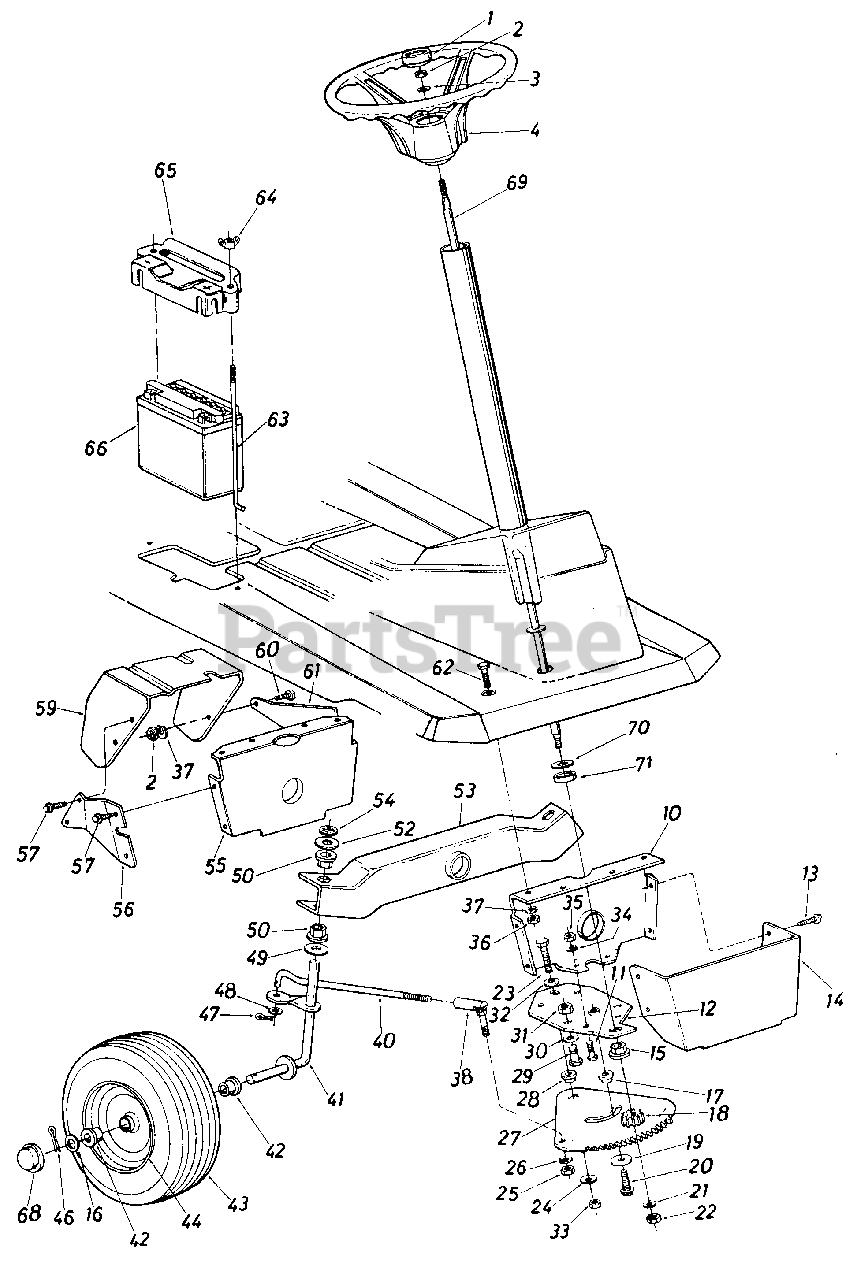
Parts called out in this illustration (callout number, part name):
1	Steering Wheel Cap
2	Hex Nut 5/16-18 Thd
3	Bell-Wash. .345" I.D. x .88" 0. D.
4	Steering Wheel Ass'y
10	Pivot Bar Bracket
11	Hex Bolt 5/16-18 x .75" Lg.
12	Steering Gear Support Brkt.
13	Hex Wash. Hd. AB-Tap Scr. 1/4 X .62" Lg
17	Shoulder Spacer .622 Dia. x .218
18	Steering Pinion Gear
19	Fl-Wash. .385" I.D. x 1.38"
20	Hex Wash. Hd. Self-Tap Scr. 3/8-16 x 1.25" Lg.
21	Fl-Wash. .34" I.D. x .68" O.D.
22	Hex Nut 5/16-24 Thd.
23	Hex Bolt 3/8-24 x 1.25" Lg. (Grade 5)
24	Fl-Wash. .385" I.D. x 1.38"
25	Hex Nut 3/8-24 Thd.
26	L-Wash. 3/8" I.D.
27	Steering Gear Segment
28	Shoulder Spacer .622" Dia. x .218
29	Hex Bolt (Nylon) 1/2-13 x .75"
30	Fl-Wash. .530" I.D. x .930"
31	Hex Nut 1/2-13 Thd
32	Bell-Wash. .385" I.D. x .88"
33	Hex Nut 3/8-24 Thd.
34	L-Wash. 5/16" I.D.
35	Hex Nut 5/16-18 Thd.
38	Ball Joint Ass'y. 3/8-24 Thd.
40	Steering Tie Rod
41	Front Axle Ass'y. R.H.
42	Flange Bearing .632" I.D.
43	Front Wheel Ass'y. Comp.
44	Front Wheel Rim Only
46	Cotter Pin 1/8" Dia. x 1.25"
47	Cotter Pin 1/8" Dia. x 1.00"
48	Fl-Wash. .385" I.D. x .87"
49	Fl-Wash. .635" I.D. x 1.12"
50	Hex Flange Bearing
52	Fl-Wash. .635" I.D. x 1.12"
53	Pivot Bar Ass'y.
54	Speed Nut 518" I.D.
55	Pivot Bar Bracket
56	Bracket Reinforcement R.H.
57	Hex Wash. Hd. AB-Tap Scr. 1/4 x.62" Lg.
59	Clutch-Brake Pedal Ass'y.
60	Hex Bolt 5/16-18 x .75" Lg.
61	Bracket Reinforcement L.H.
62	Hex Bolt 5/16-18 x .75" Lg.
63	Battery Hold Down Rod
64	Wing Nut Solid 1/4-20 Thd.
65	Battery Hold Down Cover
66	12V Battery
68	Plastic Hub Cap
69	Steering Shaft Ass'y.
70	Fl-Wash. .62" I.D. x 1.50" O.D.
71	Spacer (Plastic)
